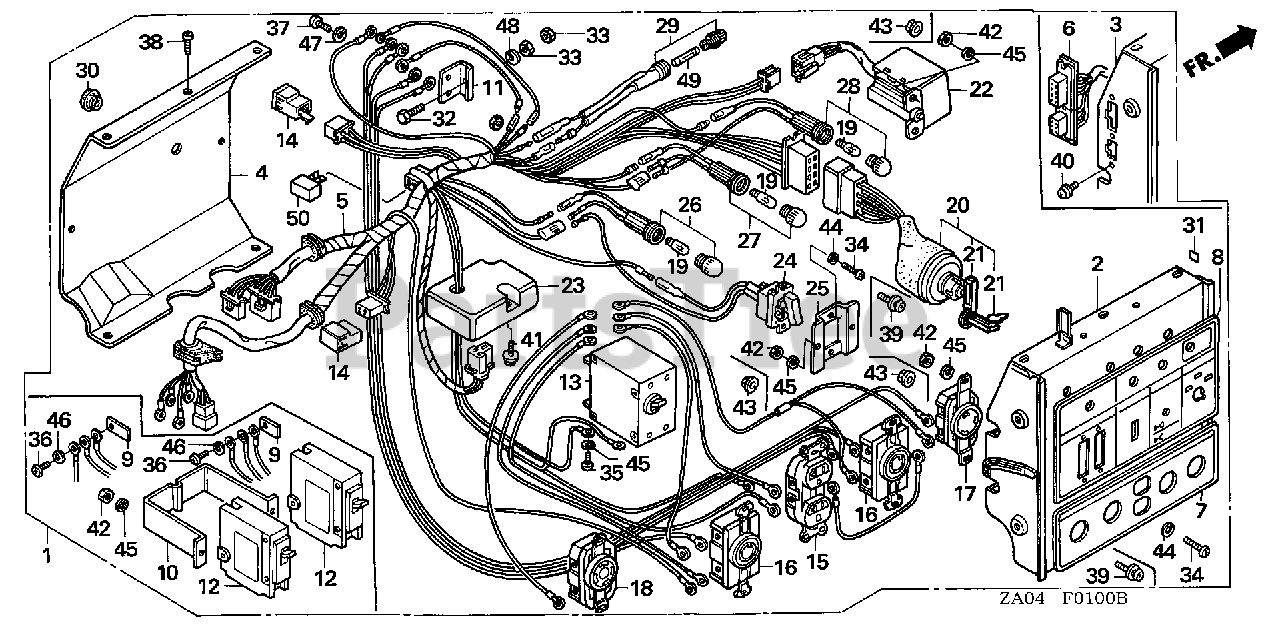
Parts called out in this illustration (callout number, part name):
1	BOX ASSY., CONTROL *NH105* (MAT BLACK)
2	PANEL, FR. *NH105* (MAT BLACK) (NOT AVAILABLE)
2	PANEL, FR. *NH105* (MAT BLACK) (NA USE ALT:31402-ZA0-631ZA)
5	WIRE HARNESS
7	MARK, RECEPTACLE PANEL
7	MARK, RECEPTACLE PANEL (NOT AVAILABLE)
8	MARK, SWITCH PANEL
9	TERMINAL, BREAKER
10	SUPPORT, BREAKER
11	PLATE, GROUND
12	BREAKER, CIRCUIT (27A) (NOT AVAILABLE)
13	BREAKER, CIRCUIT (27A)
14	STACK ASSY., DIODE (2.7A)
15	RECEPTACLE ASSY. (20A/125V) (MATSUSHITA)
15	RECEPTACLE (20A/125V)
16	RECEPTACLE (20A/125V) (NOT AVAILABLE)
17	RECEPTACLE (30A/125V)
18	RECEPTACLE (30A/125-250V)
19	BULB, DASH (24V-2W)
20	SWITCH ASSY., COMBINATION
21	KEY
22	RELAY, ALERT
23	CONTROL UNIT, IDLE
24	SWITCH ASSY., IDLE CONTROL
25	STAY, SWITCH
26	SOCKET ASSY., PILOT LAMP
27	SOCKET ASSY., LAMP
28	SOCKET ASSY., LAMP
29	HOLDER, FUSE
30	GROMMET, TOP COVER
31	MARK, GROUND
32	BOLT, HEX. (8MM)
33	NUT, HEX. (8MM) (NOT AVAILABLE)
34	SCREW, PAN (3X8)
35	SCREW, PAN (4X8)
36	SCREW, PAN (5X10)
37	SCREW, PAN (6X12)
38	SCREW-WASHER (4X8)
39	SCREW-WASHER (3X6)
41	SCREW-WASHER (5X10)
42	NUT, HEX. (4MM)
44	WASHER, SPRING (3MM)
45	WASHER, SPRING (4MM)
46	WASHER, SPRING (5MM)
47	WASHER, SPRING (6MM)
48	WASHER, SPRING (8MM)
49	FUSE B (15A)
